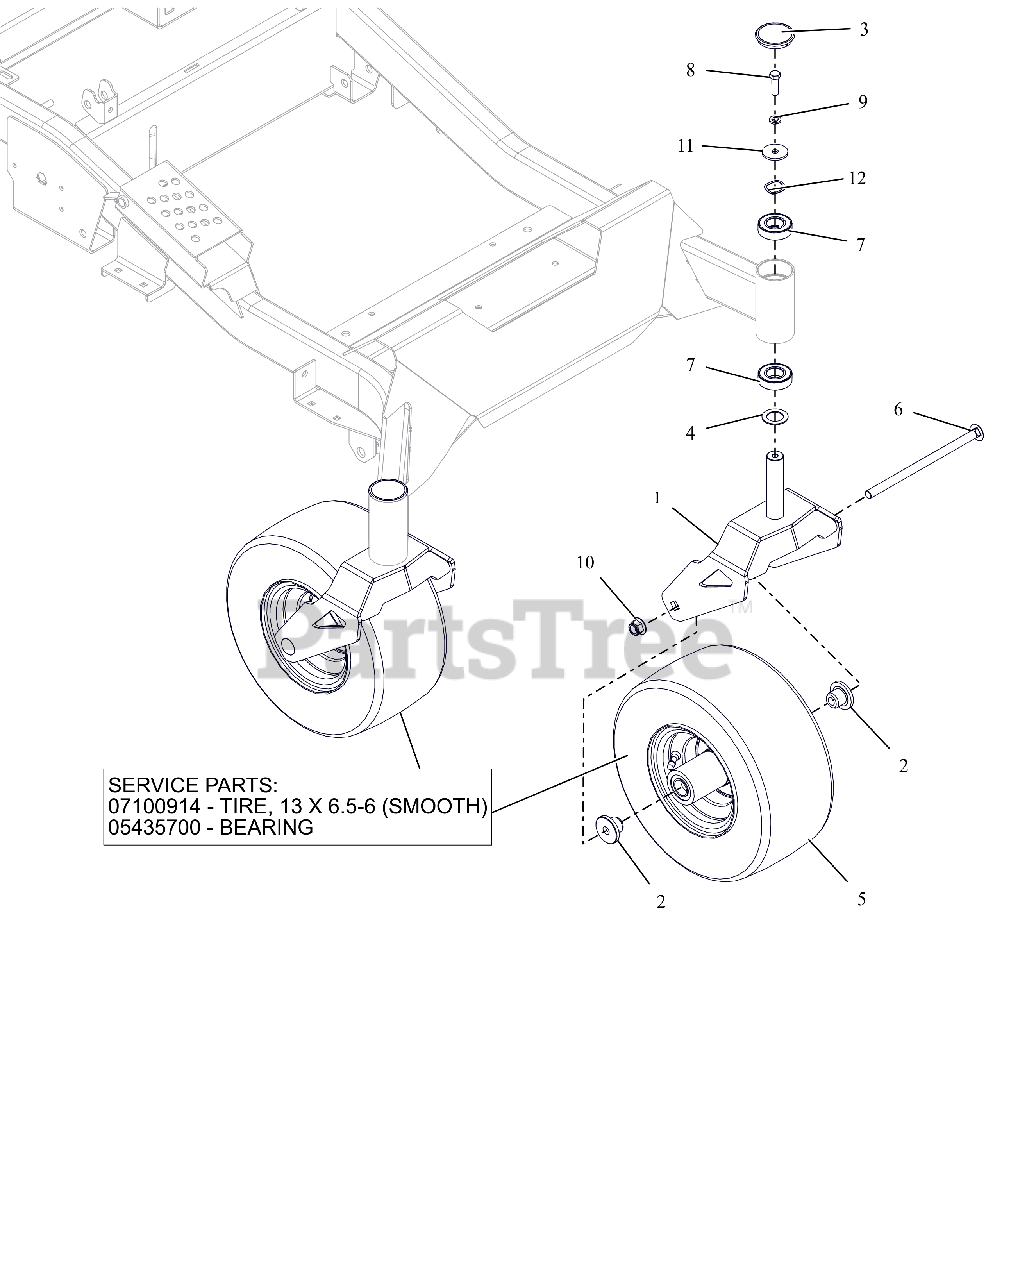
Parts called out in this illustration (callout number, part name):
1	WLDMT, HD CASTER FORK
2	SPACER, FRONT WHEEL
3	CAP, DUST
4	WSHR-HRD-THRS 1.007X1.542X.062
5	ASM, WHL/TIRE 13X6.50-6
5	TIRE, 13X6.50-6 SMOOTH
5	BRG, 25MM ID X 52MM OD X 15MM
6	BLT-RDHDSQNK .50-13X9.00 G5 Y
7	BRG,BALL 1.00X2.00X.563(1641)
8	@BLT-HEX .38-16X1.25 GR5 YWZC
9	WSHR-LK .375X.115 HVY YWZC
10	@NUT-LK-NYL-FLG .50-13 YWZC
11	WSHR-FL-STL .380X1.50X.125YWZC
12	WSHR-WAVE 1.0X1.25X.028 .145FH
